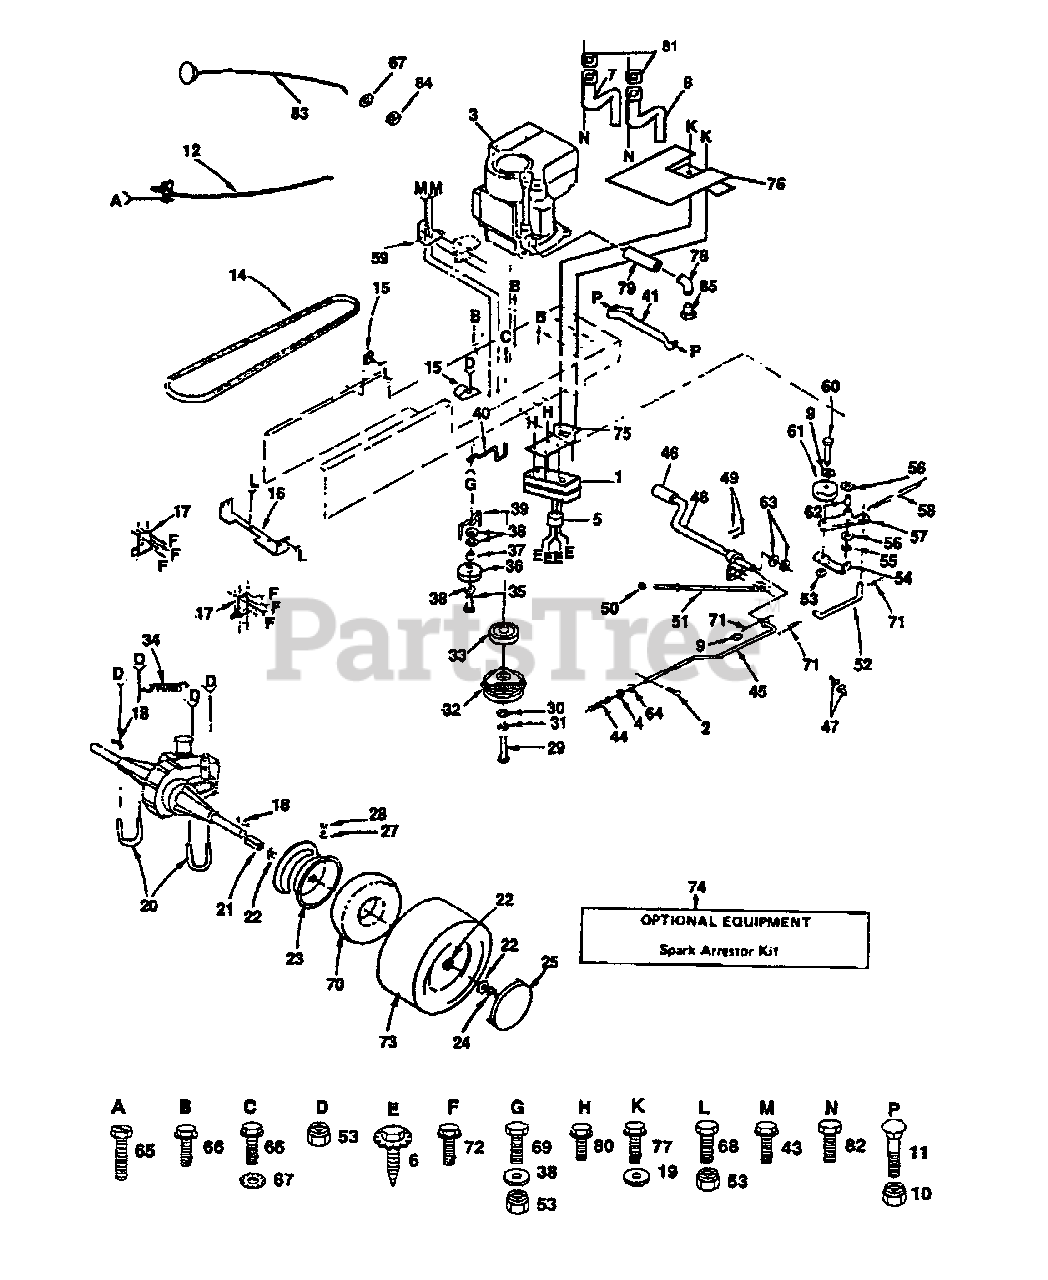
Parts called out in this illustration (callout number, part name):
2	Clip, Hairpin
4	Nut, Hex, Jam 3/8 x 16 UNC
6	Screw, Spider Lock, Hex #8 x 1/2
7	Tube Manifold, L.H.
8	Tube Manifold, R.H.
9	Washer 13/32 x 13/16 x 16 Gauge
10	Nut, Crownlock 5/16-18
11	Bolt, Carriage 5/16-18 x 3/4
12	Control, Throttle
14	V-Belt, Drive
15	Clip
16	Bracket, Mounting, Hydro T/A
17	Bracket, Transaxle
18	Key, Square 1/4 x 2
19	Washer 13/32 x 1 x 14 Gauge
20	U-Bolt 3/8-16 x 2.83
21	Spacer, Split
22	Washer 1-1/32 x 1-5/8 x 16 Gauge
23	Rim, Rear
25	Cover, Wheel
27	Stem, Valve
28	Cap, Valve
29	Bolt, Hex, Fin 7/16-20 UNF x 4 Grade 8
30	Washer 1-1/2 OD x 15/32 ID x .250
31	Washer, Lock 7/16
32	Clutch, Electric
33	Pulley, Engine
34	Spring, Brake Return
35	Soft, Hex 3/8-16 x 2-3/4
36	Idler, Flat
38	Washer 13/32 x 13/16 x 12 Gauge
39	Retainer, Belt
40	Keeper, Belt, Engine
41	Retainer, Clutch Assembly
43	Screw, Tap. Hex Hd, #10-24 x 1/2 Type T
44	Spring, Rod, Brake
45	Rod, rake
46	Cover, Pedal
47	Bearing, Nylon
48	Shaft, Foot Pedal, Assembly
49	Pin, Roll 3/16 x 1
50	Cap, Plunger
51	Rod, Brake, Park
52	Link, Clutch
53	Nut, Crownlock 3/8-16
54	Retainer, Belt
55	Ring, Klip
56	Washer, Hardened
57	Arm, Assembly, Idler
58	Spring, Return, Clutch
59	Bracket, Switch
60	Bolt, Hex 3/8-16 x 1-1/2
61	Pulley, Idler
63	Washer 21/32 x 1 x 16 Gauge
64	Locknut, Hex W/Wash 3/8-16
65	Screw, Hex Thread Cut. 1/4-20 x 5/8
66	Screw, Hex Washer Thread Rolling 3/8-18 x 1-1/2
67	Washer, Lock External Tooth 3/8
68	Soft, Hex 3/8-16 x 3/4
69	Bolt, Hex 3/8-16 x 1
70	Tube
71	Pin, Cotter 1/8 x 3/4
72	Screw, Hex, Thdrol 3/8-16 x 3/4
73	Tire
74	Spark, Arrestor Kit
75	Bracket, Muffler Mounting
76	Shield, Heat
77	Screw, Hex, Washer Thrdrol 5/16-18 x 3/4
78	Elbow, STD 90° 3/8-18 NPT
79	Nipple, Pipe
80	Screw, Hex, Washer Thrdrol. 1/4-20
81	Gasket
82	Bolt, Metric
83	Choke Control
84	Nut, Hex 3/8-24 UNF
85	Plug, Oil Drain
